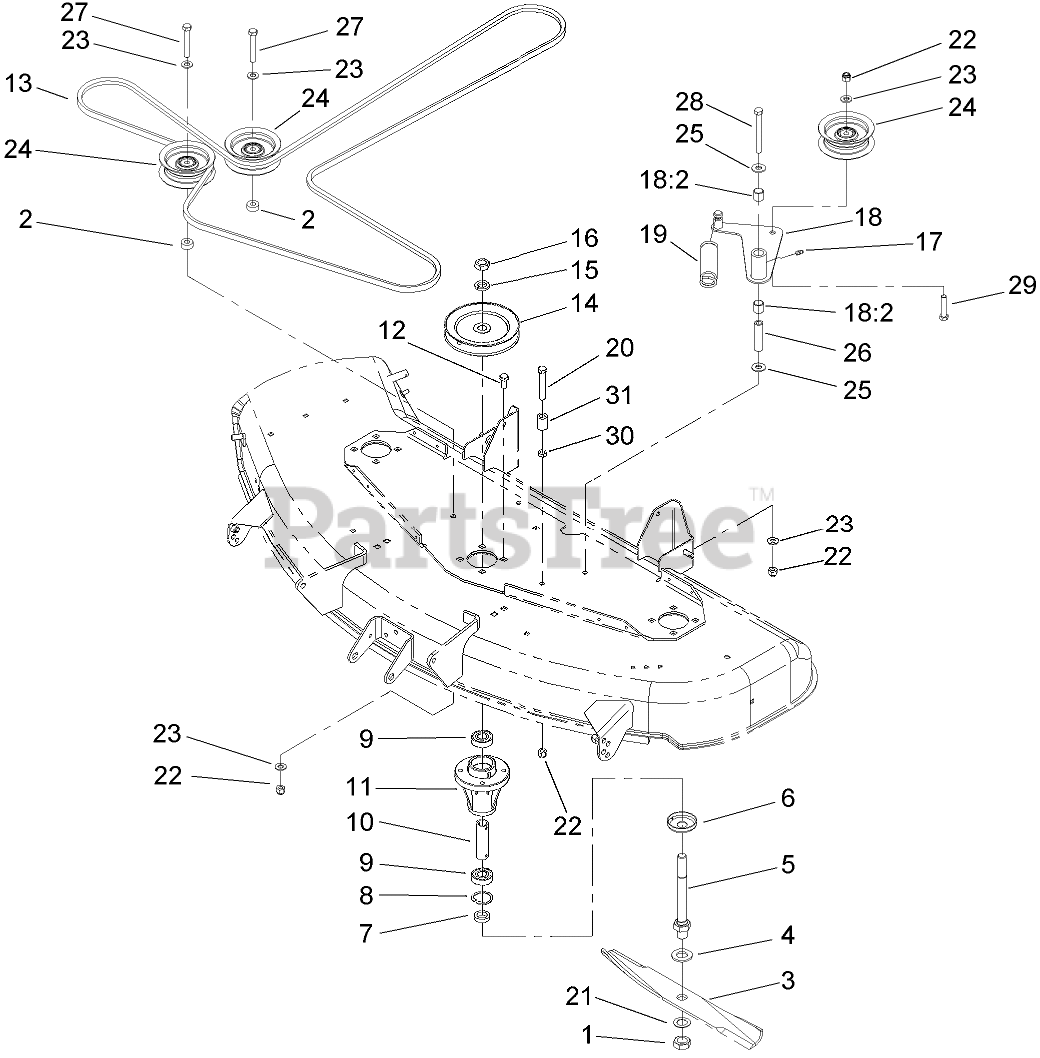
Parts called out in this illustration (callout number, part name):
1	NUT-JAM
2	SPACER
3	BLADE KIT (3 PACK)
4	WASHER-FLAT
5	SHAFT-SPINDLE
6	CUP-SPINDLE
7	SPACER-BLADE
8	RING-RETAINING
9	BEARING-BALL
11	HOUSING-SPINDLE
12	SCREW-HH
13	BELT-V
14	PULLEY ASM
15	WASHER-LOCK
16	NUT-JAM
17	FITTING-GREASE
18	IDLER ARM ASM
18:2	SLEEVE-BEARING
19	SPRING-EXTENSION
20	SCREW-HH
21	WASHER-FLAT
22	NUT-LOCK, NI
23	WASHER-FLAT
24	PULLEY-IDLER, FLAT
25	WASHER-HARDENED
26	BUSHING-PIVOT, IDLER
27	SCREW-HH
28	SCREW-HH
29	SCREW-HH
30	NUT-HEX
31	TUBE-INTERLOCK
